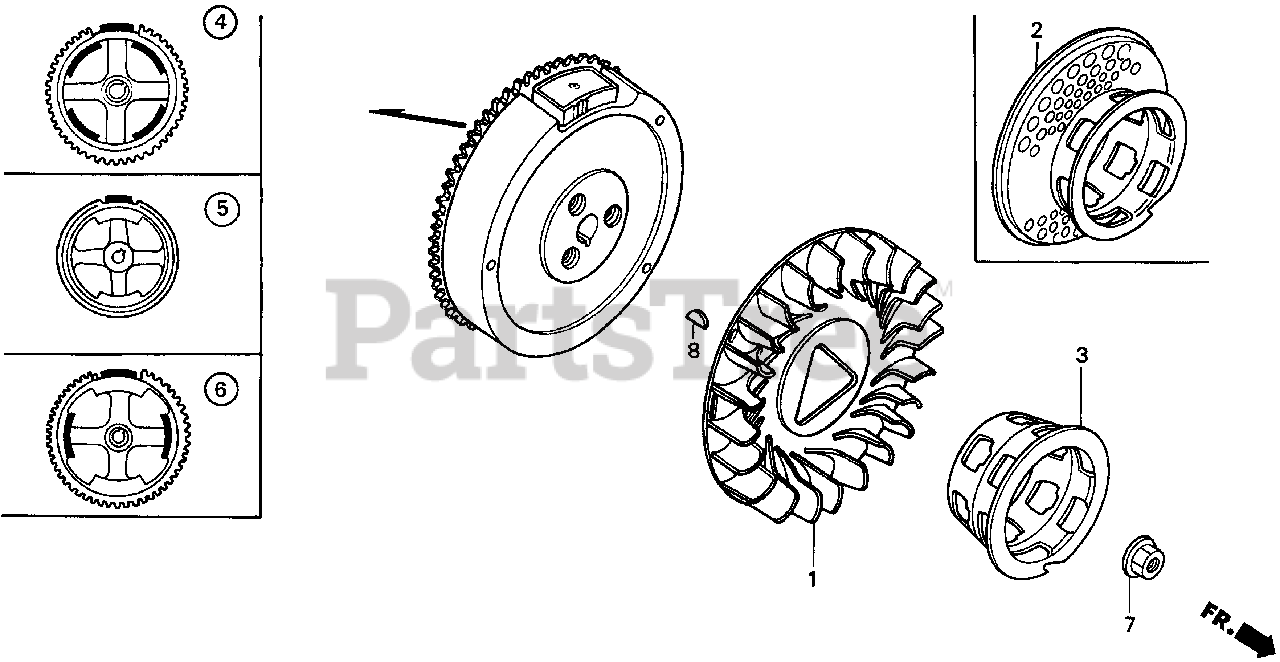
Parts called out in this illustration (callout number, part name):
1	FAN, COOLING
2	PULLEY, STARTER (SCREEN GRID)
5	FLYWHEEL (4 POLE)
7	NUT, SPECIAL (16MM) (1)
8	KEY, SPECIAL WOODRUFF (25X18)
